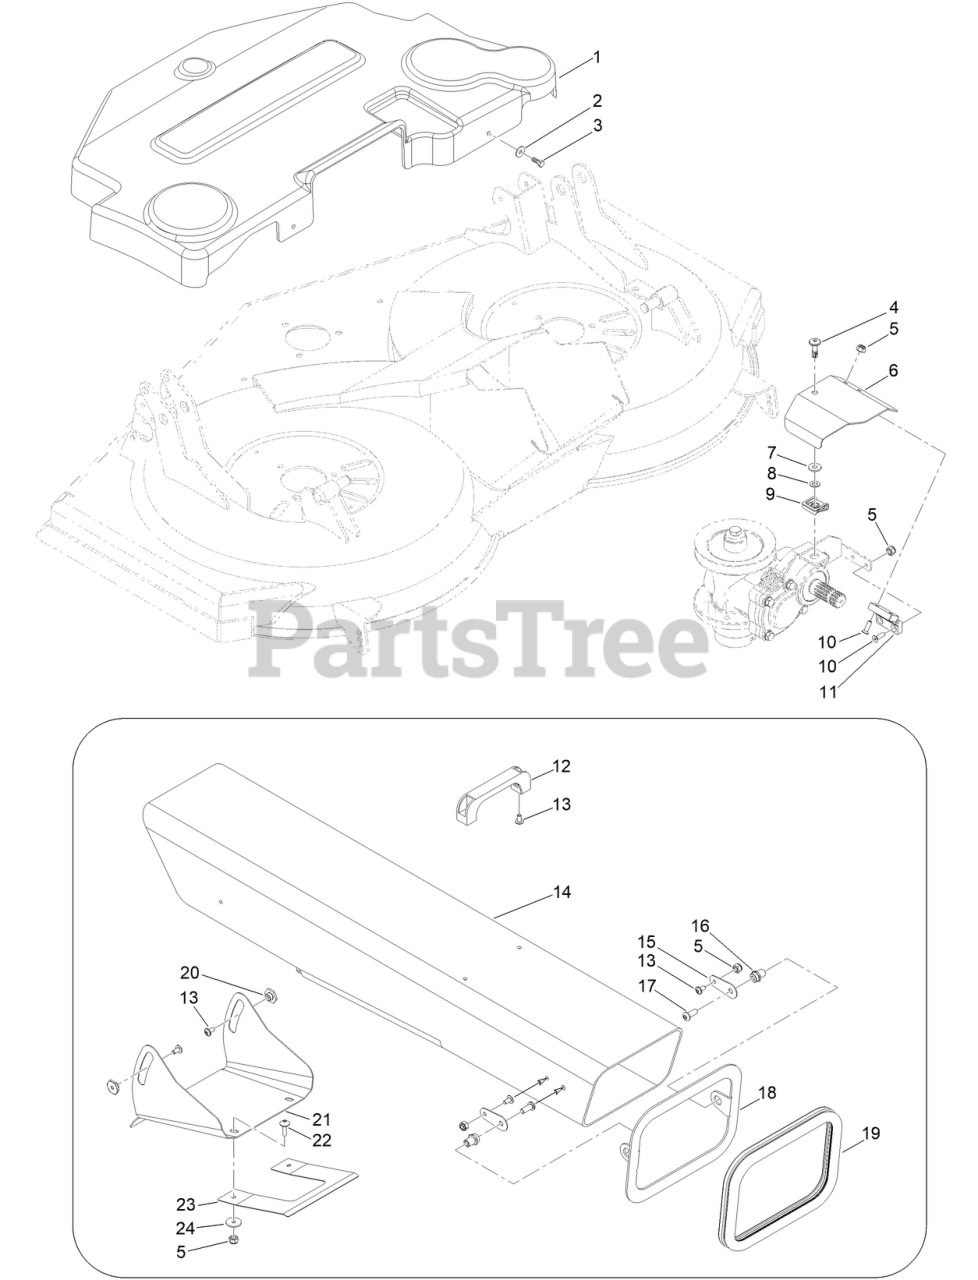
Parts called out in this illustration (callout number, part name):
1	COVER, DECK
2	WASHER
4	FASTENER-RETAINED
6	COVER, CARDAN SHAFT
7	WASHER
8	WASHER
9	PLATE-SMALL
11	HINGE-PLASTIC
12	HANDLE
15	PLATE, CHUTE
16	PIN, CHUTE
17	SCREW, H-SCKT B HEAD
18	FRAME, CHUTE
19	GASKET, CHUTE
21	BULKHEAD, CHUTE
24	WASHER
